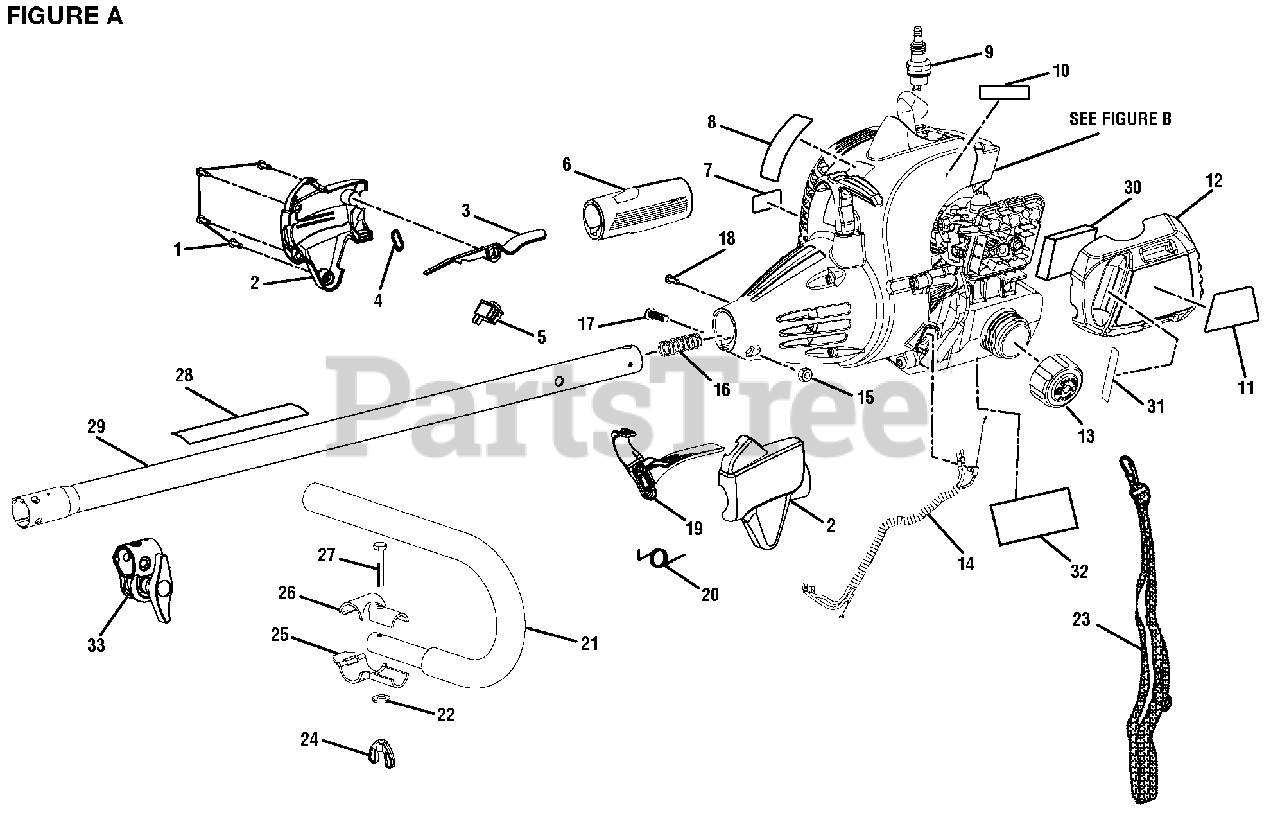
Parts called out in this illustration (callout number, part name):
1	Screw (M4 x 20 mm)
2	Control Handle Assembly
3	Trigger Lock
4	Strap Hanger
5	Switch (Momentary Contact)
6	Rear Handle
7	Combustion Warning Label
8	Logo Label
9	Spark Plug (Champion RCJ6Y)
10	Primer Label
11	Starting Label
12	Air Box Cover
13	Fuel Cap Assembly (1.5 in. Diameter)
14	Throttle and Lead Assembly
15	Hex Nut (M6)
16	Compression Spring
17	Bolt (M6 x 20 mm)
18	Screw (M4 x 8 mm., Torx T.F.)
19	Throttle Trigger
20	Throttle Spring
21	"J" Handle and Grip
23	Shoulder Harness
24	Wing Nut (1/4-20)
25	Bottom "J" Handle Clamp
26	Top "J" Handle Clamp
27	Bolt (1/4-20 x 1-1/2 in., Hex Hd.)
28	Warning Decal
29	Upper Boom Assembly
30	Air Filter
31	Run Start Label
32	Fuel Tank Warning Label
33	Boom Clamp
